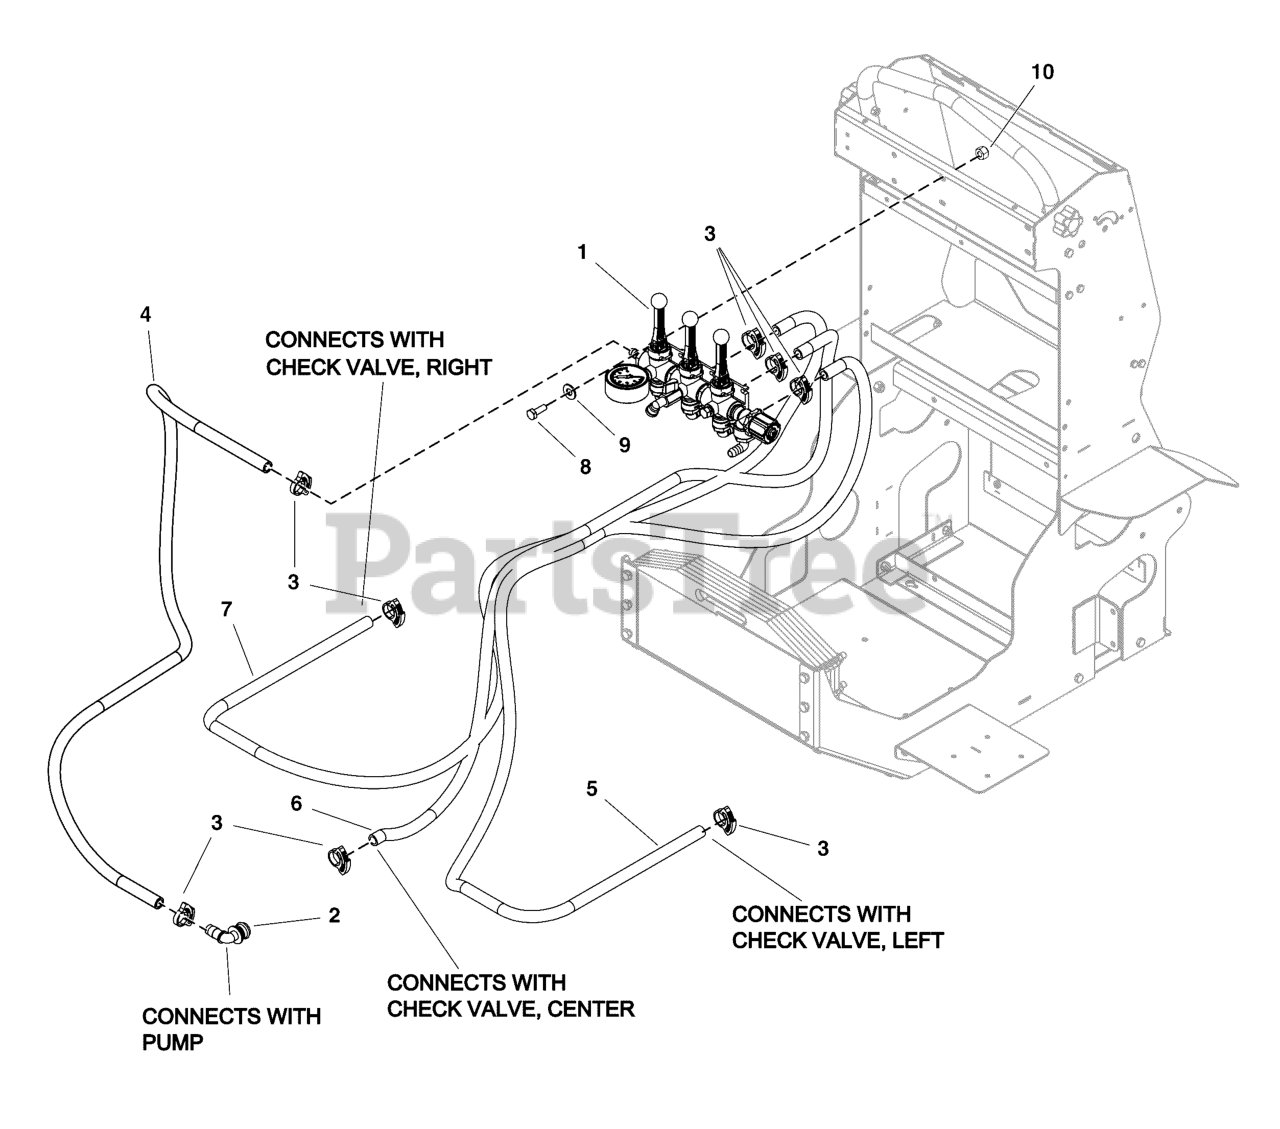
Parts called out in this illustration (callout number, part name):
1	REFER TO: SPRAY TOGGLE VALVE ASSEMBLY GROUP
2	FITTING, ELBOW, 3/4 QA - 1/2 BARB
3	SNAP GRIP CLAMP .656 - .750 ID
3	CLAMP, PINCH 19.8mm TO 22.6mm
4	HOSE, VALVE INLET, 0.5" ID, 54" LONG
4	HOSE, CHEM .50 X56"
5	HOSE, LEFT BOOM, 0.5" ID, 86" LONG
5	HOSE, CHEM .50" X 87"
6	HOSE, CENTER SPRAY, 0.5" ID, 61" LONG
6	HOSE, CHEM .50" X 64"
7	HOSE, RIGHT BOOM, 0.5" ID, 84" LONG
7	HOSE, CHEM .50 x93"
8	SCR-CAP, HEX .250"-20 X .750" SS188
9	WSHR-STL, FLT .281" X .625" X .050" IS SS188
10	NUT-HEX-NYLK, .250"-20 SS188
